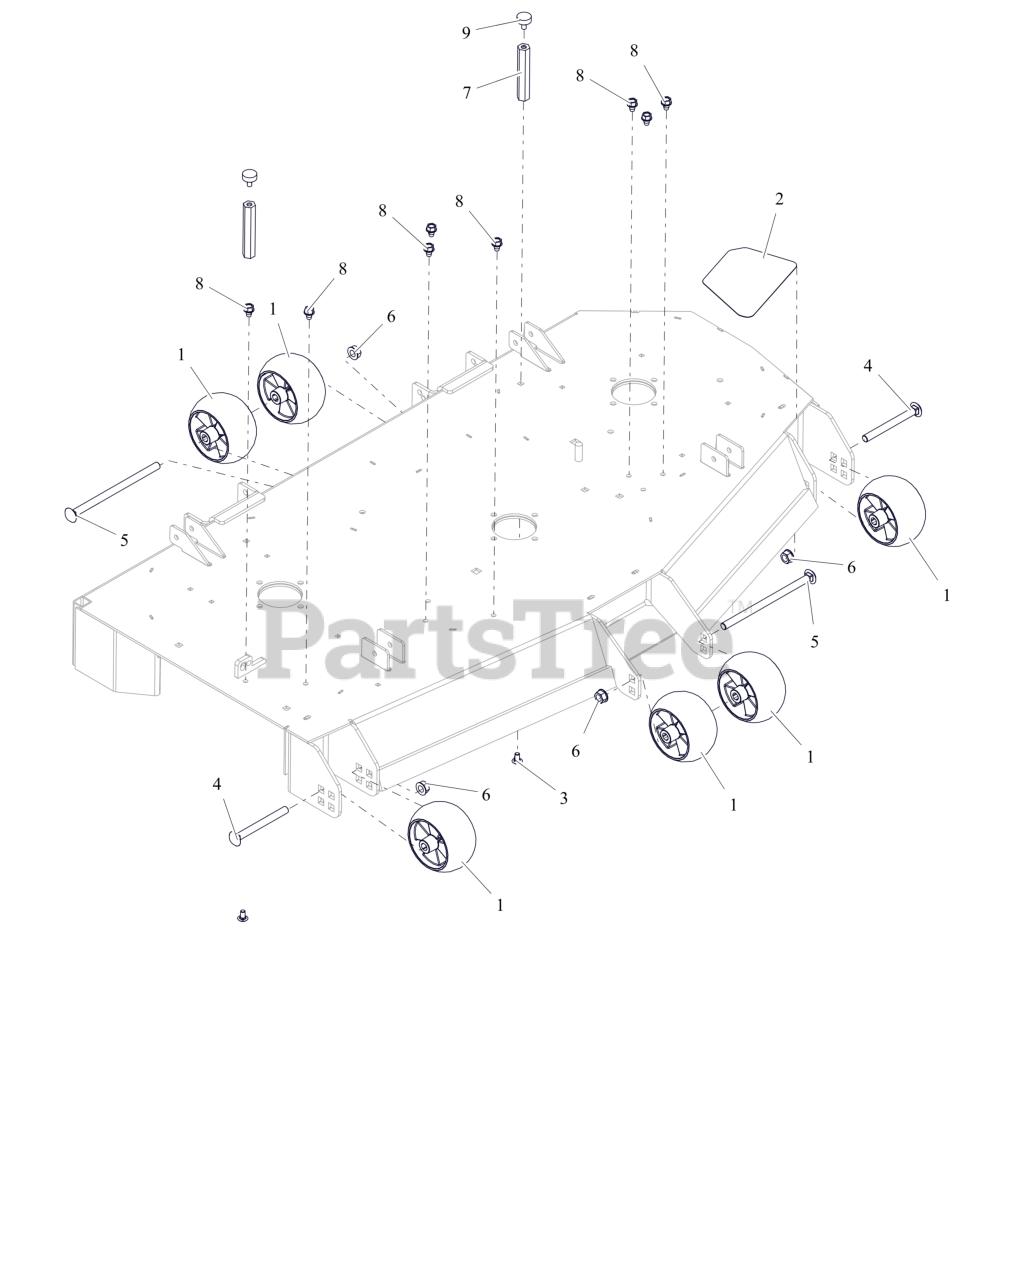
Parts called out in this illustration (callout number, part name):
1	WHEEL, ANTI SCALP - 5X3 CTR W/RIBS
2	GRIP, STEP ANTI SKID
3	BTL,RHSSN .313-18 X 0.625 G5 ZCC
4	BLT, RHSN .50-13X5.00 G5 ZCC
5	BTL,RHSN .500-13 X 8.5S G5 ZCC
6	NUT-LK-CTR-FLG .500-13 GG ZCC
7	NUT, COUPLING .312-18 X 4.295
8	SCR,TAP .375-16X.50 HWH TR ZCC
9	BUMPER, RUBBER
